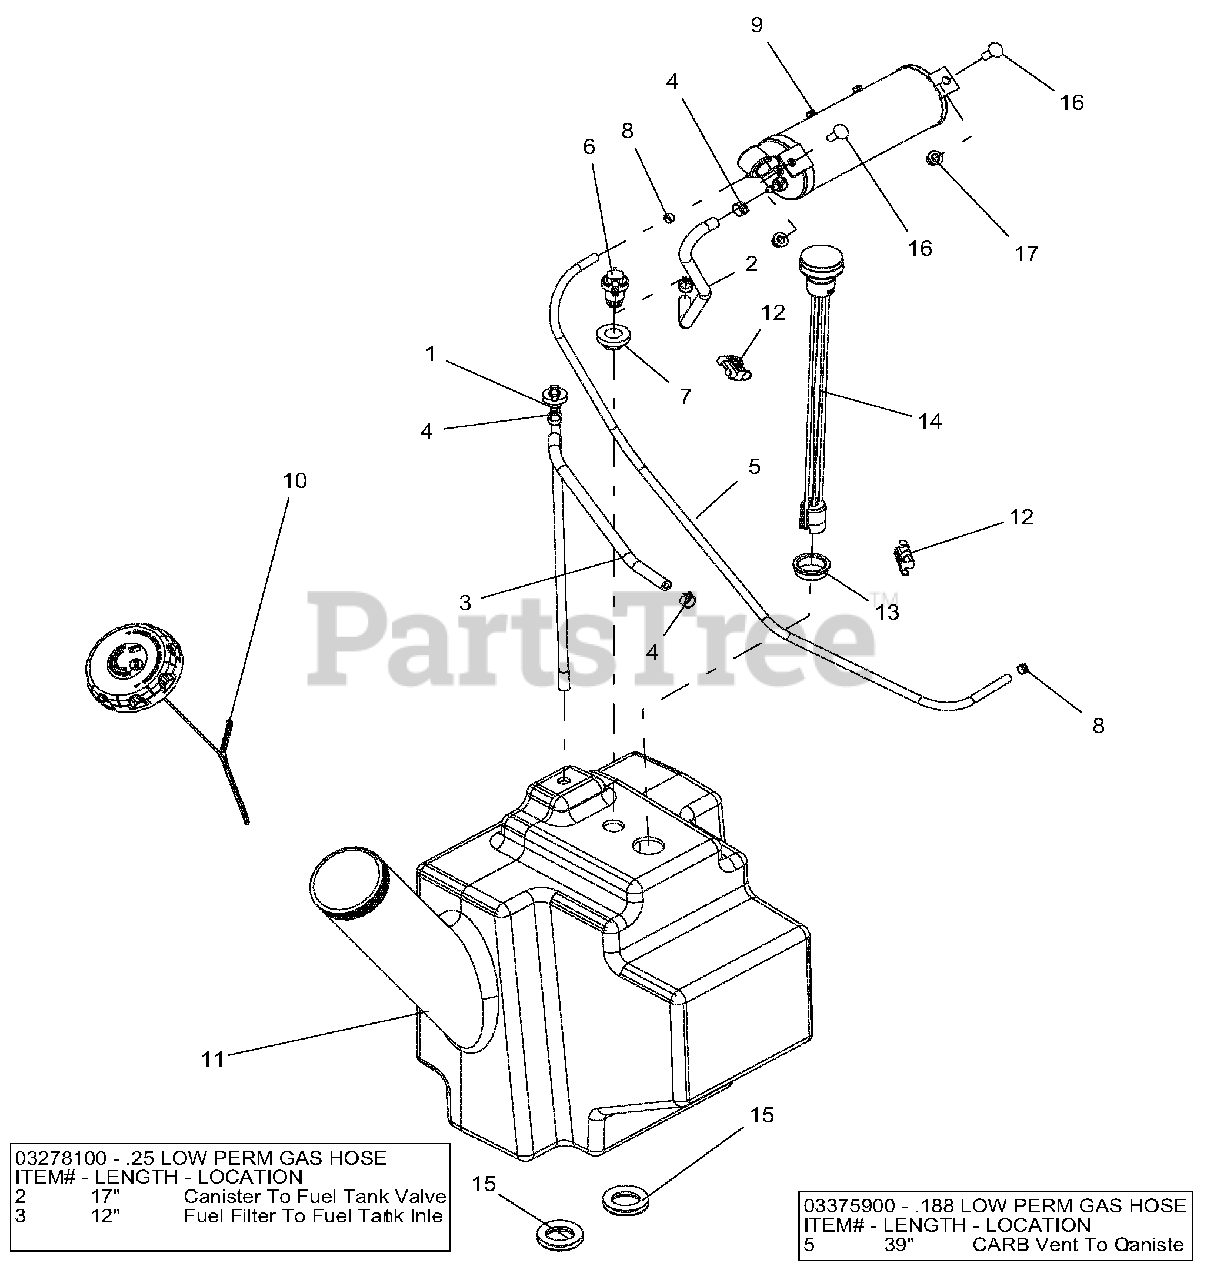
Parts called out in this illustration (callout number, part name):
1	ASM, LARGE TANK FUEL PICK-UP
2	.25 LOW PERM GAS HOSE
3	.25 LOW PERM GAS HOSE
4	CLAMP, FUEL LINE
5	HOSE, .188 LOW-PERM BULK GAS
6	VALVE, COMBINATION
7	GROMMET, REMOTE VENT NITRILE
8	CLAMP - HOSE, SPRING .188
9	CANISTER, CARBON 9.3 GAL
10	CAP, NON NONVENT AUTOLOCK
11	TANK, FUEL COMPACT PROSTANCE
12	CLIP, T, .38-.50
13	GROMMET, FUEL GAUGE
14	GAGE, REMOTE FUEL SEALED 15"
15	GROMMET, 1.25"
16	BLT-RDHDSQSHNK .31-18X1.00 G5 Y
17	NUT-LK-NYL-FLG .31-18 YWZC
